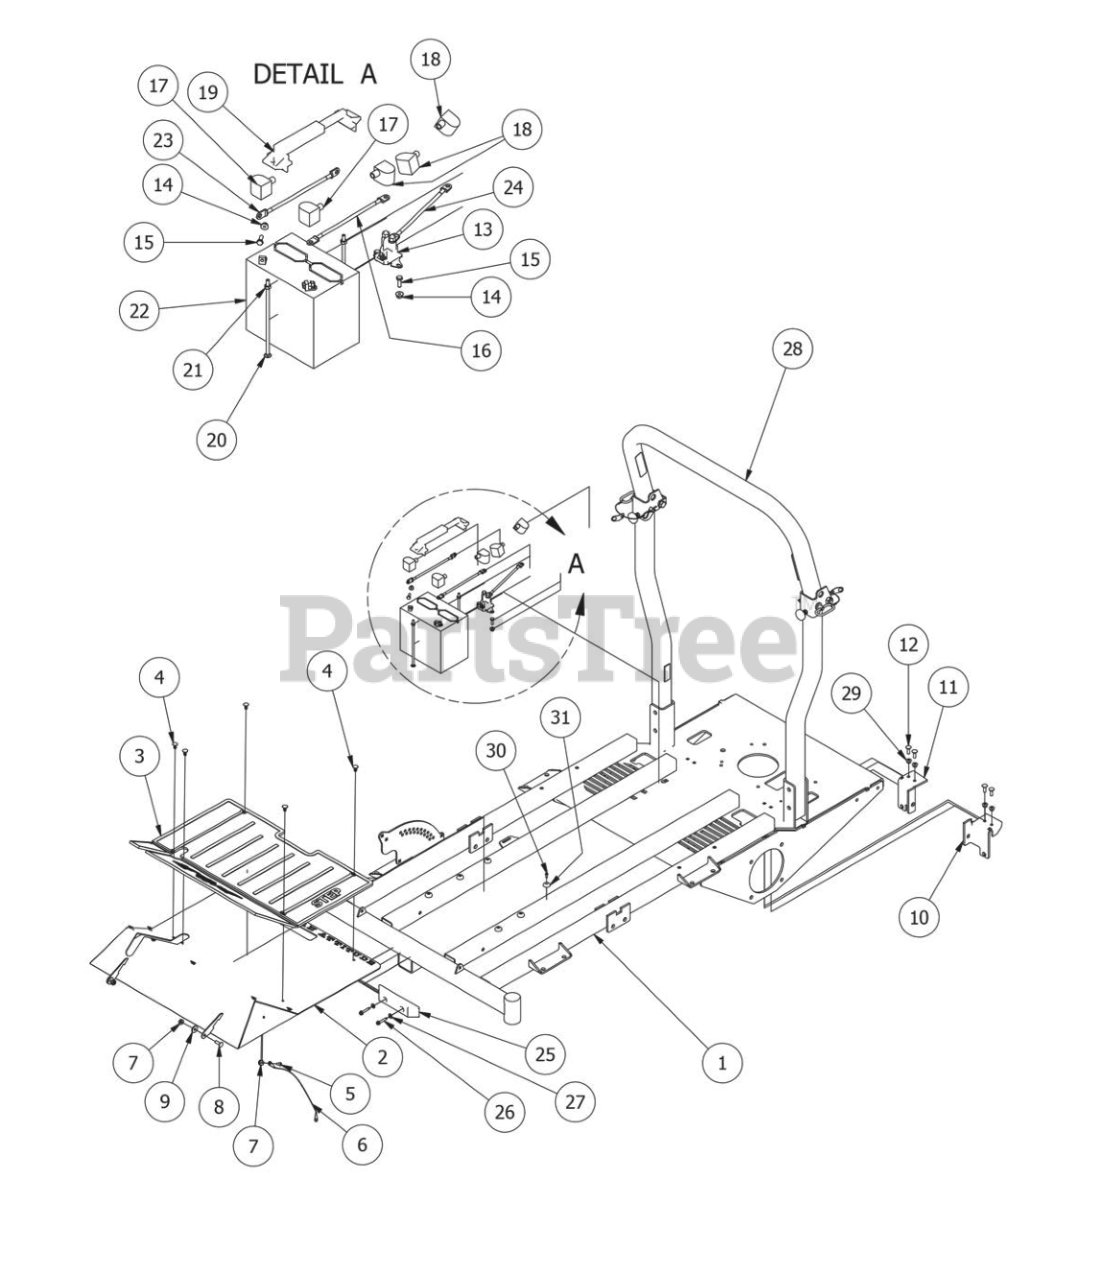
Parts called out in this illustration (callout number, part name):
1	Outlaw Frame
2	Outlaw Floor Panel
3	Foot Assist Floor Mat
4	Ratchet Fastener
5	1/4" x 5/8" BS C/S 18-8 SS
6	Floor board Cable W/ Swivel Ends
7	5/16-18 Nylon Flange Nut
8	5/16" x 1" Carriage Bolt
9	.360 ID Plastic Washer
10	Outlaw Brake Cable Mount Bracket (Right)
11	Outlaw Brake Cable Mounting Bracket (left)
12	5/16" x 1" Carriage Bolt
14	1/4-20 Hex Flange Nuts Zinc w/Serrations
15	1/4-20 x 3/4 GR 5 Hex Bolts Zinc
16	24" red battery cable
17	Black Boot For ground cable
19	Battery Hold Down
20	1/4-20 X 8 Carriage Bolt
21	1/4-20 Hex Nut
23	Starter to chassis cable
24	Red battery cable alternator to Started cable
25	8" Rubber Bumper
26	1/4" x 1 1/2" Self Tapping Screw
27	1/4" Flat Washer
28	Outlaw-2010 and Up
29	5/16" Nylon Flange Nut
30	#10 x 1/2" Self Taping Screw
31	Button Bumper
